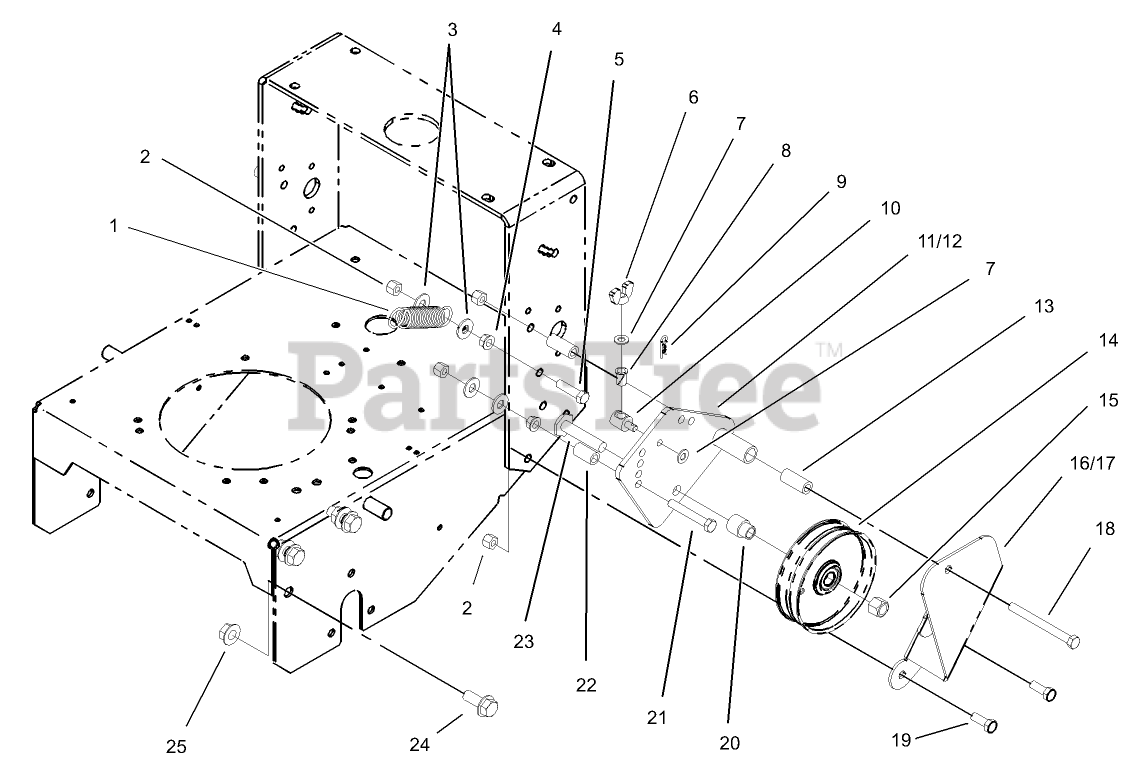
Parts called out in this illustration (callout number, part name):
1	SPRING-EXTENSION
2	NUT-LOCK, NI
3	WASHER-FLAT
4	NUT-FLANGE
5	SCREW-HH
6	NUT-WING
7	WASHER-PLAIN
8	BUSHING-NYLON
9	PIN-COTTER
10	FITTING-ROD
11	LH IDLER BRACKET ASM
12	RH IDLER BRACKET ASM
13	SPACER-PIVOT, IDLER
14	PULLEY-IDLER
15	NUT-LOCK, NI
16	BRACKET-SUPPORT, LH
17	BRACKET-SUPPORT, RH
18	SCREW-HH
19	SCREW-HH
20	SPACER-PULLEY
21	SCREW-HH
22	SPACER
23	SCREW-LEVELER
24	SCREW-HHF
25	NUT-HF
